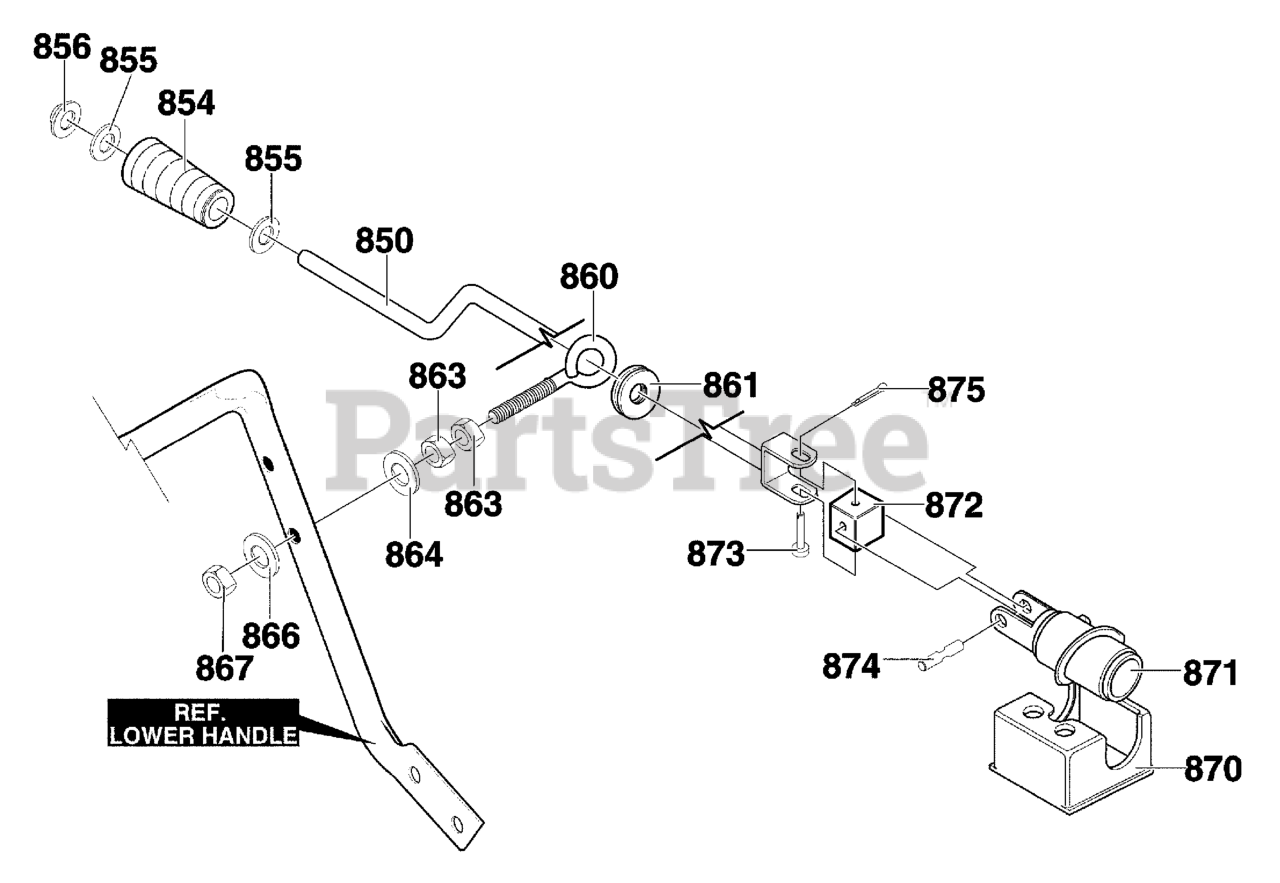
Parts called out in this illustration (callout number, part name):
850	CRANK, ASSY CHUTE
854	KNOB, SLEEVE
855	FLATWASHER
856	NUT, PUSH ON 3/8"
860	EYE BOLT 3/8-16X6.00
861	GROMMET, EYE BOLT
863	NUT, 3/8-16 HEXJAM
864	FLATWASHER .406X.81X.066
866	FLATWASHER .406X.81X.066
867	NUT, 3/8-16 HEXNYL
870	BRACKET, WORM MTG
871	WORM, GEAR CHUTE ROTATION
872	BLOCK, UNIVERSAL PIVOT
873	CLEVIS PIN
874	PIN, UNIVERSAL JOINT
875	COTTER PIN
